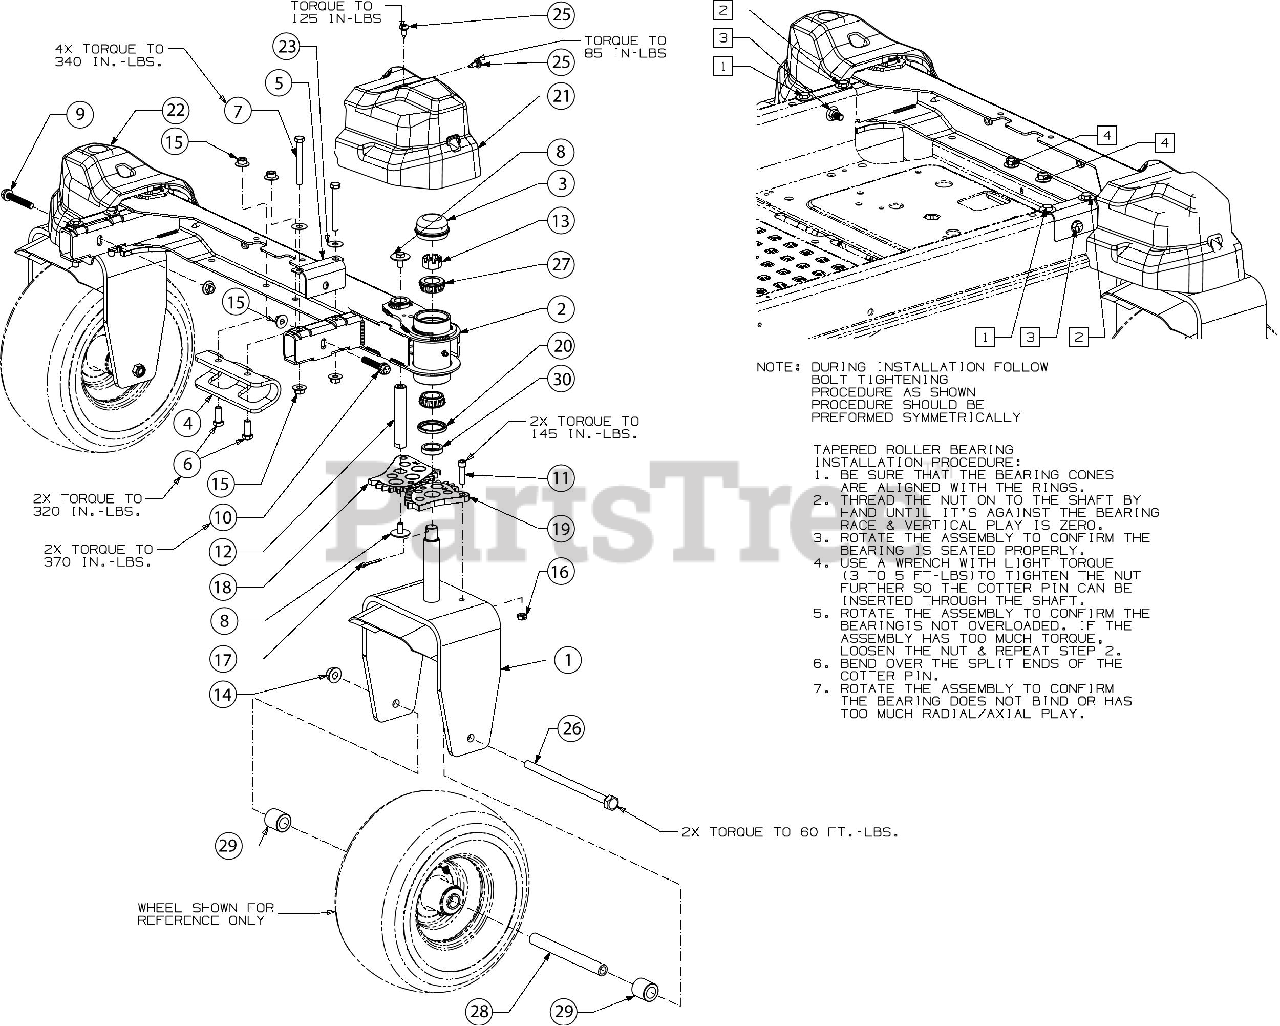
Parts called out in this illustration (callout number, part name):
2	FRONT AXLE
3	AXLE GREASE CAP
6	SCREW 3/8-16 x 1 GR5
7	SCREW 3/8-16 x 3 GR8
8	SCREW 5/16-18 X.75 GR5
9	SCREW 3/8-16 x 2.25 GR5
10	SCREW 3/8-16 x 2.00 GR5
11	SCREW 5/16-18X1.25
12	STEERING GEAR PIVOT SHAFT
13	HEX NUT CASTLE 3/4-16
15	FLANGE LOCK NUT
16	HEX NUT
17	COTTER PIN-5/32 DIA
18	STEERING GEAR
19	STEERING SPUR GEAR 13T
21	AXLE COVER (RH)
22	AXLE COVER (LH)
23	FLAT WASHER
25	TORX SHOULDER SCREW 1/4-20
26	SCREW 1/2-13X8.5 GR5 FLG
27	ROLLER BEARING 47MM x 25MM x 15MM
28	CASTER AXLE SPACER
29	SPACER .76X1.23X1.25
